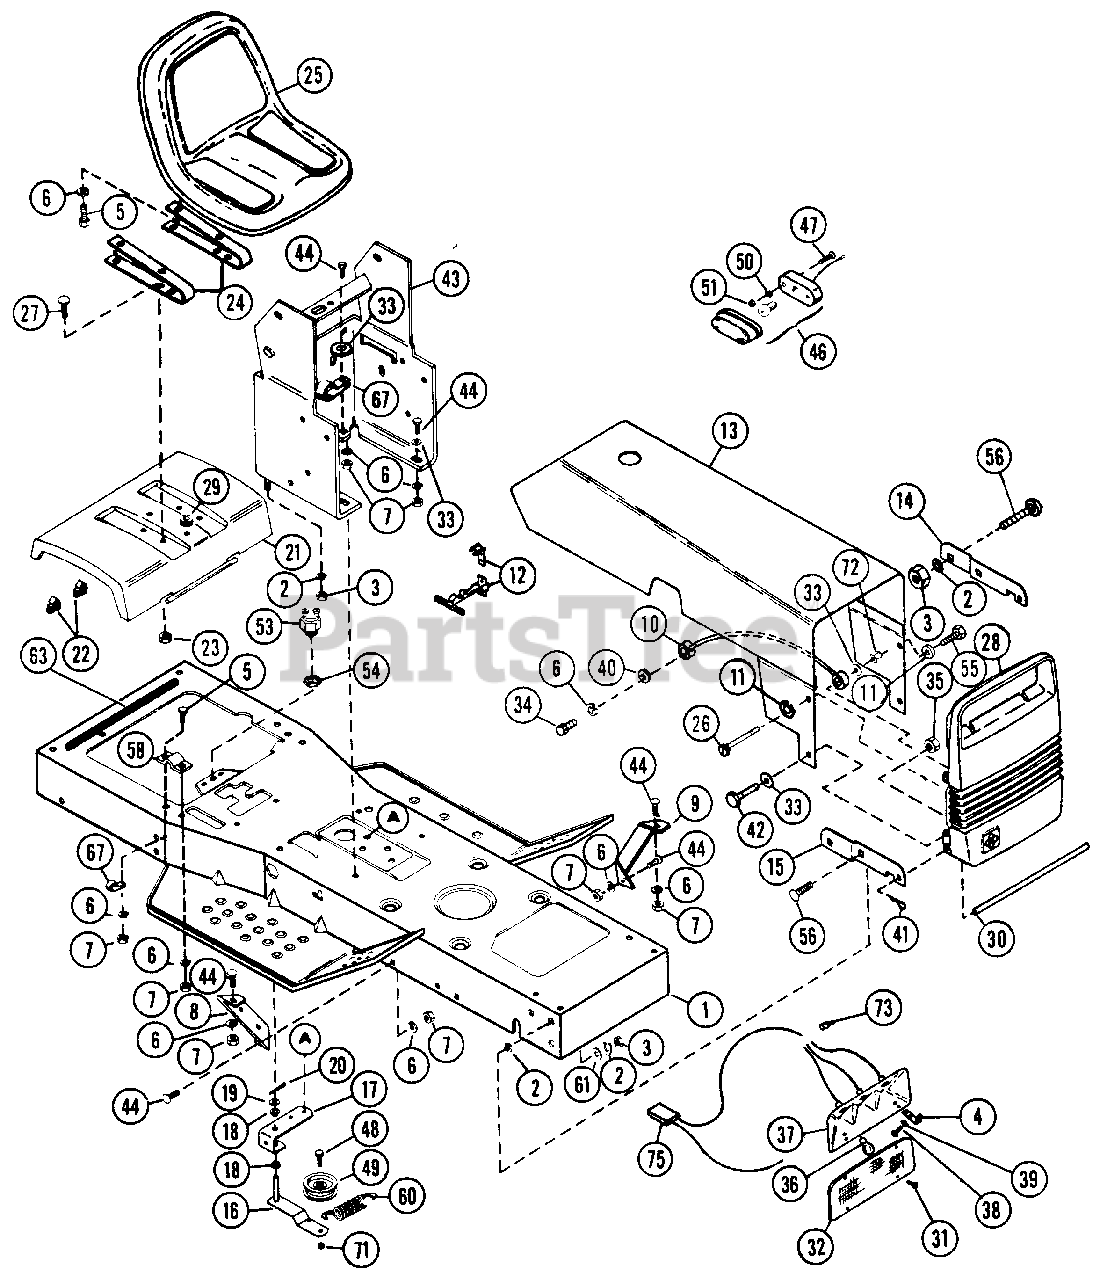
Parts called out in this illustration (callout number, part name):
2	WASHER, LOCK 3/8 REG.
3	NUT, HEX 3/8-16
4	CLIP, LIGHT MOUNTING
5	BOLT, HEX 5/16-18X.75
6	WASHER, LOCK 3/8 SP HEAVY
7	NUT, HEX 5/16-18
8	STRUT RIGHT FOOT BOARD
9	STRUT LEFT FOOT BOARD
10	HOOD LANYARD
11	WASHER, FLAT .250X.500X.049
12	DRAW LATCH ASSEMBLY
13	WELDMENT, HOOD
14	BRACKET, HOOD PIVOT(L.H.)
15	BRACKET, HOOD PIVOT(R.H.)
16	IDLER ARM
17	IDLER PIVOT
18	FLANGE BUSHING
19	WASHER, FLAT .406X.812X.065
20	PIN, COTTER .125X1.00
21	REAR DECK
22	BUMPER
23	NUT, LOCK 5/16-18
24	SPRING, SEAT
25	SEAT, HIGH BACK
26	BOLT, HEX 1/4-20X1.375
27	BOLT, CARRIAGE 5/16-18X.75
28	CASTING, GRILLE
29	GROMMET
30	ROD, HOOD PIVOT
31	SCREW, MACHINE 10-24X.50
32	PANEL, FRONT LIGHT
33	WASHER, FLAT .312X.734X.065
34	BOLT, HEX 5/16-18X.875
35	NUT, LOCK 5/16-18
36	LAMP, NO. 1073
37	ASSEMBLY, LAMP REFLECTOR
38	SCREW, MACHINE 10-24X.75
39	WASHER, FLAT .188X.562X.049
40	WASHER, FLAT .313X.875X.065
41	COTTER, HAIR PIN
42	BOLT, HEX 5/16-18X1.25
43	DASH BASE
44	BOLT, CARRIAGE 5/16-18X.75
46	TAIL LIGHT ASSEMBLY
47	SCREW, MACH. 10-24X.625
48	BOLT, HEX 3/8-16X1.50
49	IDLER
50	WASHER, LOCK NO. 10 SP
51	NUT
53	SWITCH, INTERLOCK-SHIFT
54	NUT, HEX 9/16-18
55	BOLT, HEX 1/4-20X.875
56	BOLT 3/8-16X1.00 RD HD SQ NK
58	BRACE
60	SPRING
61	WASHER, FLAT .438X1.000X.083
63	FOAM TAPE
67	J-CLAMP
71	NUT, LOCK 3/8-16
72	NUT, LOCK 1/4-20
73	NUT, WIRE
75	HEADLIGHT WIRING HARNESS
